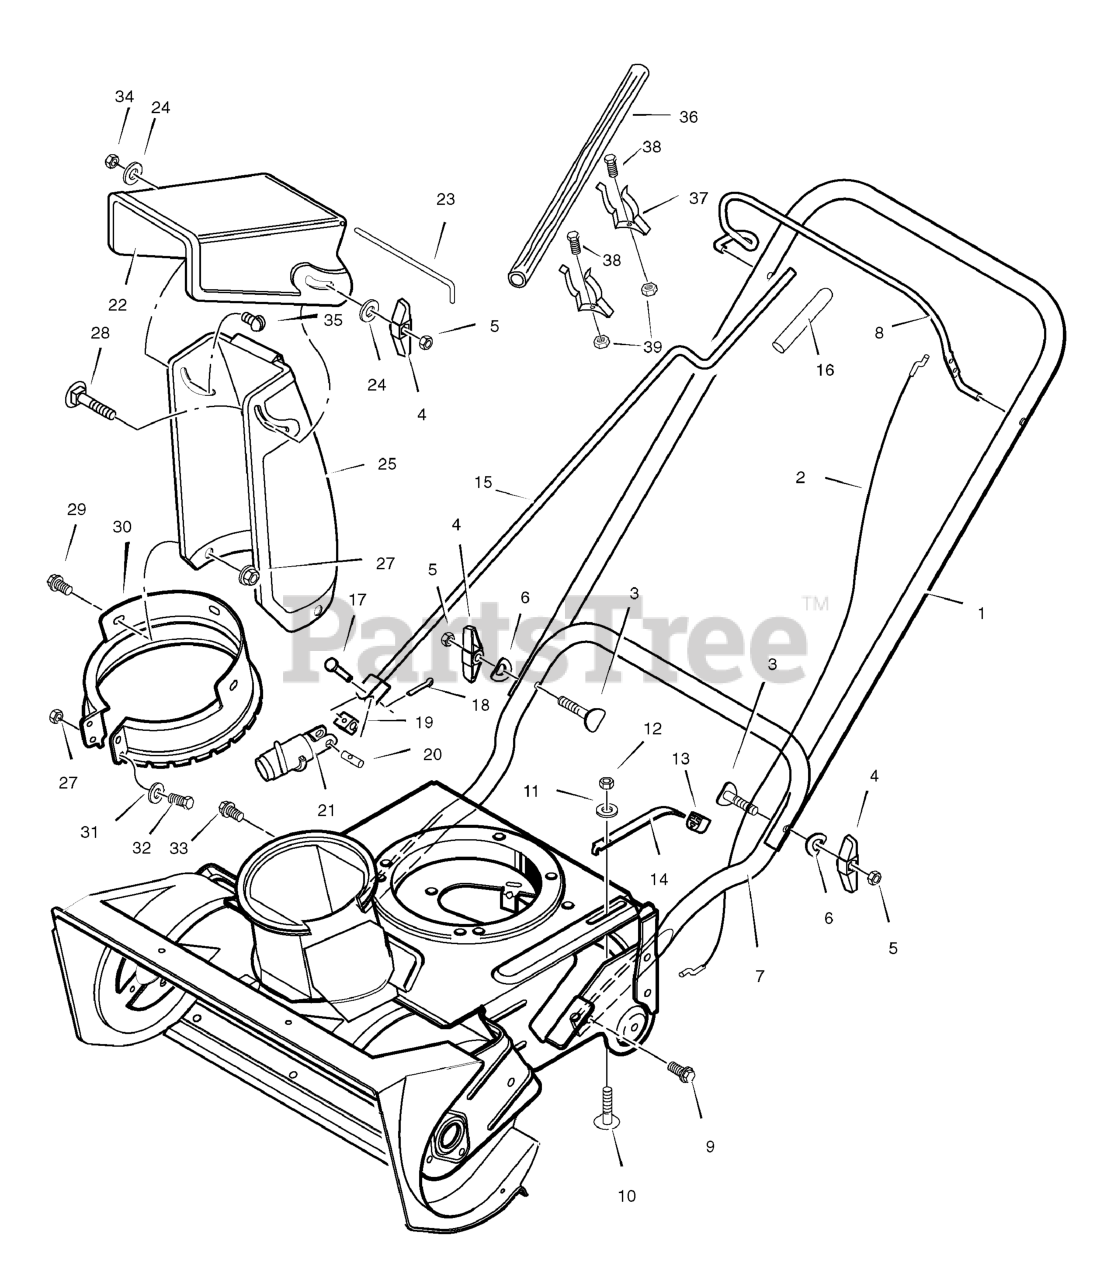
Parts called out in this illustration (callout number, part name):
1	Handle, Upper
2	Cable, Auger Drive
4	Knob
5	Nut
7	Handle, Lower
8	Lever, Auger Drive
9	Screw
13	Bushing, Tensioner
14	Bracket, Cable Tensioner
15	Rod, Crank
16	Grip, Crank Rod
17	Pin, Clevis
18	Pin, Cotter
19	Block, Universal Pivot
21	Gear, Worm
22	Chute, Upper Deflector
23	Pin, Pivot
24	Washer
25	Chute, Lower Discharge
30	Ring, Chute
31	Washer
33	Bolt
34	Locknut
36	Tool, Clean-out
37	Clip, Retainer
38	Screw, 10-32 x 1.25
39	Nut, 10-32
